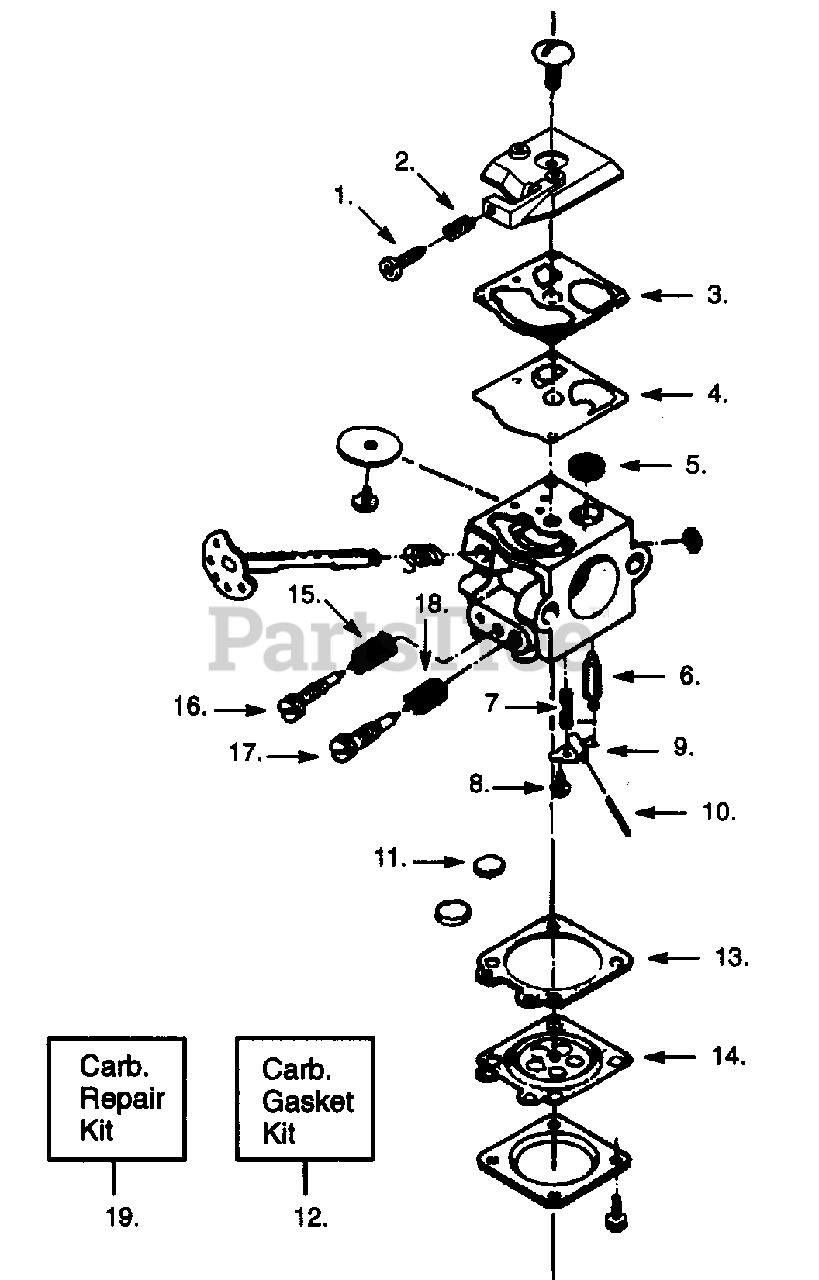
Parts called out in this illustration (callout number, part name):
1	Idle Speed Adj. Screw
2	Idle Speed Adj. Spring
3	Fuel Pump Gasket
4	Fuel Pump Diaphragm
5	Fuel Inlet Screen WT-3
6	Inlet Needle Valve
7	Metering Lever Spring
8	Metering Lever Pin Screw
9	Metering Lever
10	Metering Lever Pin
11	Welch Plug-5/16 Dia.
12	Carb. Gasket/Diaphragm
13	Metering Diaphragm Gasket
14	Metering Diaphragm
15	Low Speed Mixture Needle Spring
16	Low Speed Mixture Needle
17	High Speed Mixture Needle
18	High Speed Mixture Needle Spring
19	Carb. Repair Kit
